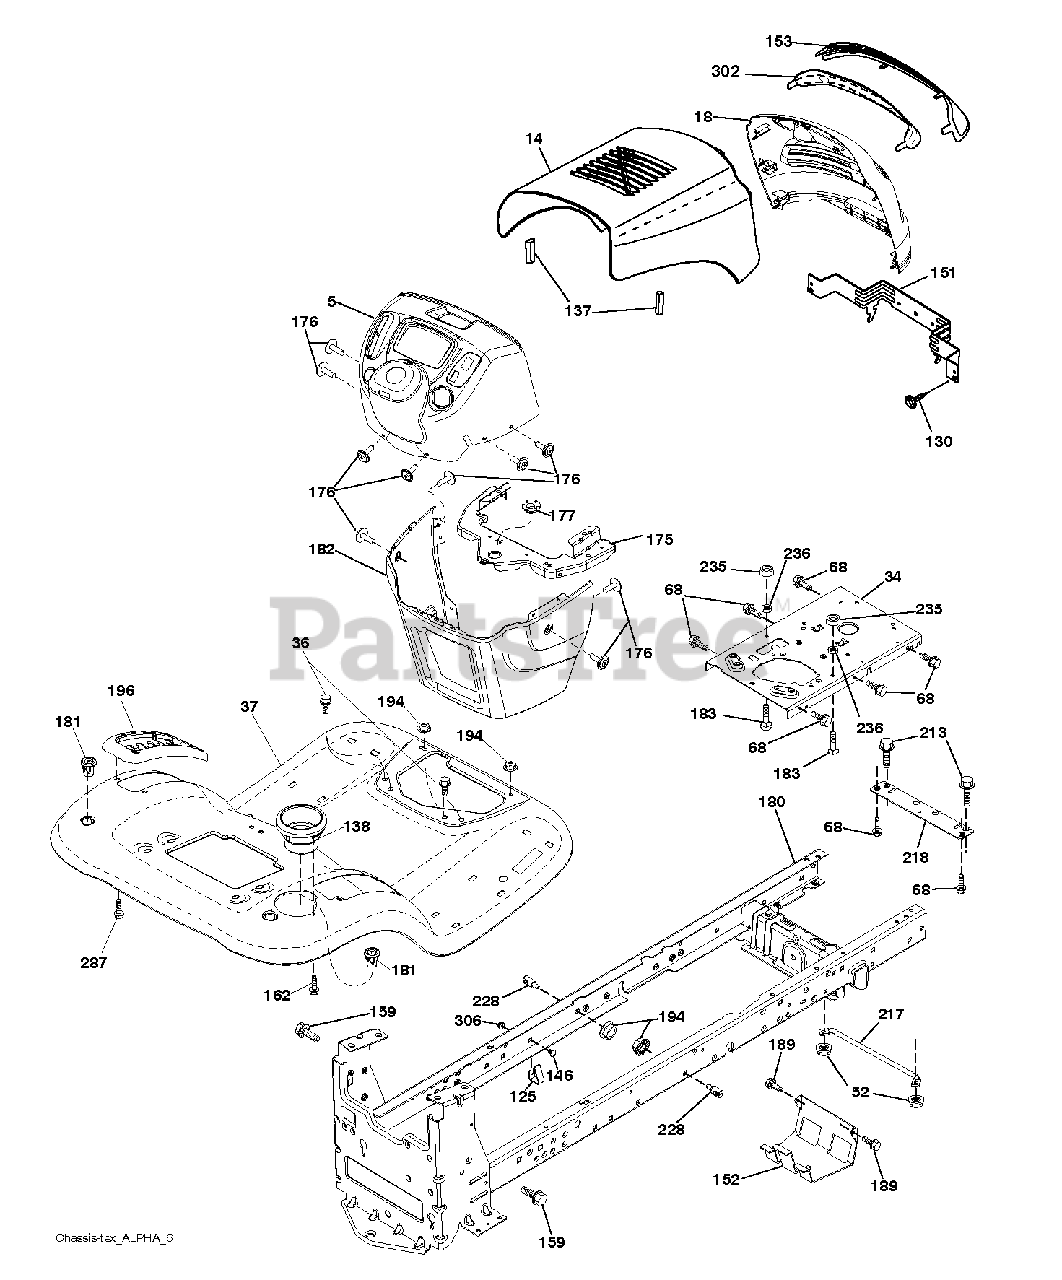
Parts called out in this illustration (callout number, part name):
5	DASH.P/L.TEX.CBL.CL.N/CHK.BLAC
14	HOOD.BLACK.ALPHA
18	GRILLE.ASM.ALPHA
34	PLATE.ENGINE.WELDED.CHASSIS
36	SCREW 5/16"
37	FENDER.TLT.FS.W/CPH.428
52	LOCKNUT
68	SCREW LT
125	CLIP.FUEL.LINE
130	SCREW.#10 X 0.750.BOS (2 2)
137	BUMPER.HOOD.LARGE.1.75"
138	CUPHOLDER.TL.TEX.BLACK
146	BOLT.RDHD.SHT.SQNK.3/8-16X5/8
151	BRACKET.PIVOT.ALPHA.LT
152	SHIELD.BROWNING.W/TEX
153	LENS.ALPHA.BAR.LT
159	SCREW, 3/8-16X3/4
162	SCREW.HI-LO.CONSOLE
175	CROSSMEMBER.LT
176	SCREW.#10-24X5/8.RN.QU
177	BUSHING STEERING
180	CHASSIS
181	SHIELD.DEFLECTOR.MOWER.42"BLAC
182	DASH.LOWER.LT.CCS
183	BOLT.5/16-18X1-1/4 FULL THD
189	SCREW
194	NUT LOCK HEX FLANGE 5/16-18
196	CONSOLE.ASM.DECKLFT.BL/RBT.TLT
213	BOLT
217	ROD.PIVOT.HOOD
218	X-PIECE.HOOD.STOP.NON/
228	STUD.FASTNER.W/ANTI-ROTATE
235	SPACER FENDER
236	NUT.CENTERLOCK.5/16-
287	SCREW 1/4X20
302	INSERT.ALPHA.REFLECTIVE.LT.
306	NUT LOCK FLG 3/8-16 UNC
